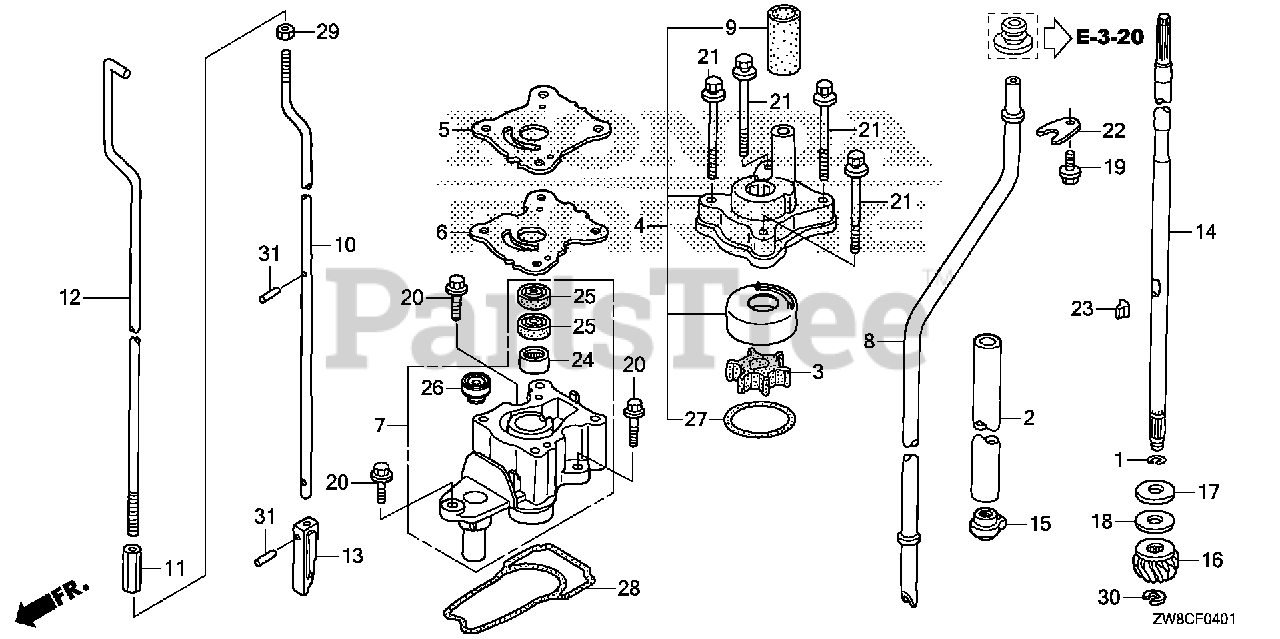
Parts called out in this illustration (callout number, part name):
1	CLIP, VALVE GUIDE
2	GUIDE, OIL (UL)
3	IMPELLER, PUMP (UL)
4	HOUSING ASSY., IMPELLER
5	COVER, IMPELLER
6	GASKET, IMPELLER
7	HOUSING, WATER PUMP (UL)
8	TUBE, WATER (UL)
9	RING, WATER TUBE SEAL
10	ROD B, SHIFT (UL)
11	JOINT, SHIFT ROD
12	ROD A, SHIFT (L)
13	ROD, PUSH
14	SHAFT, VERTICAL (UL)
15	SLINGER, OIL (UL)
16	GEAR, PINION
17	WASHER A, THRUST BEARING
18	WASHER B, THRUST BEARING
18	WASHER C, THRUST BEARING
19	BOLT, FLANGE (6X12)
20	BOLT, FLANGE (6X20)
21	BOLT-WASHER (6X90)
22	PLATE, WATER TUBE SETTING
23	KEY, WOODRUFF
24	BEARING, NEEDLE (15X21X12)
25	SEAL, WATER (15X24X5)
26	SEAL, WATER (6MM)
27	O-RING (42.2X2.4)
28	O-RING, WATER PUMP HOUSING
29	NUT, HEX. (6MM)
30	E-RING (8MM)
31	ROLLER (2.5X11.8)
